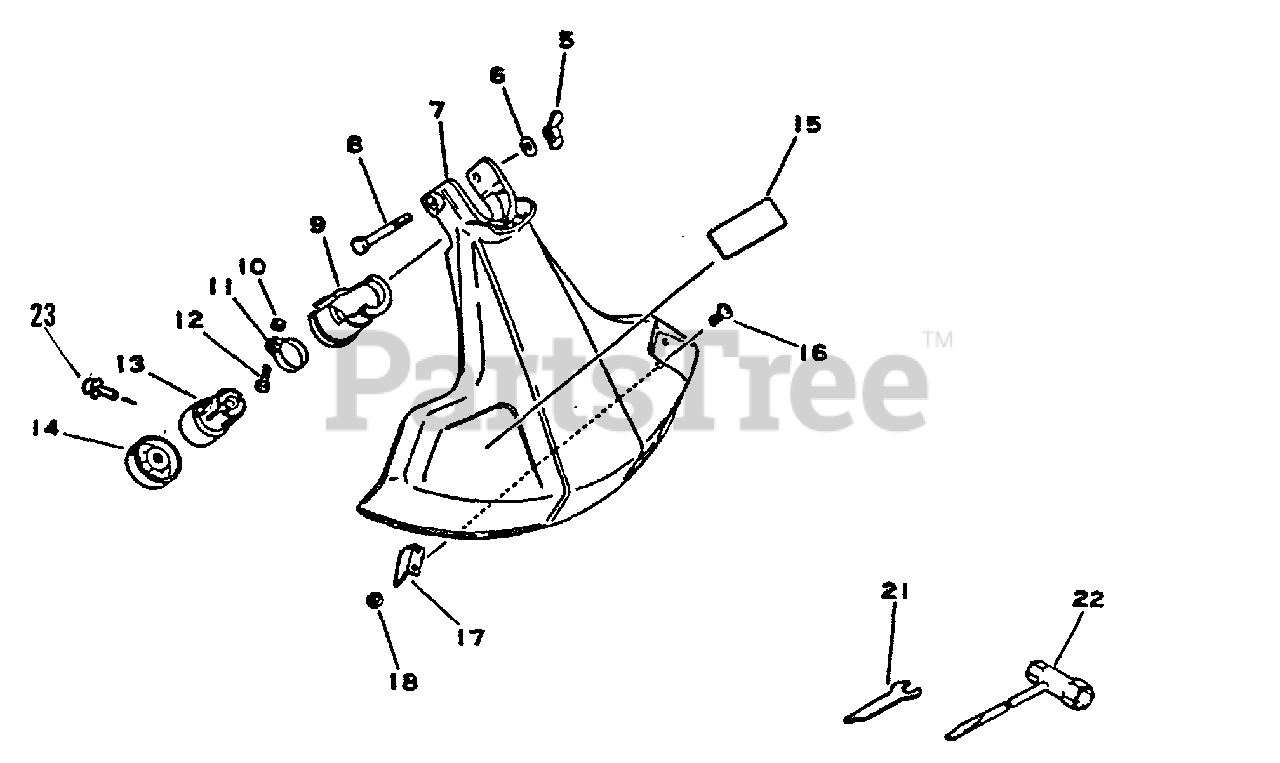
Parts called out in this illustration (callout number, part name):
5	NUT, WING 6
6	WASHER 6.5×11.5×0.8
7	SHIELD
8	BOLT - 6×50
9	BRACKET, BEARING CASE
10	NUT M5
13	GEAR CASE ASSY
14	PLATE, ADAPTER - UPPER
15	LABEL - ECHO
16	SCREW 5×16
17	CUTTER, LINE
18	NUT M5
22	WRENCH
23	SCREW 4×10
